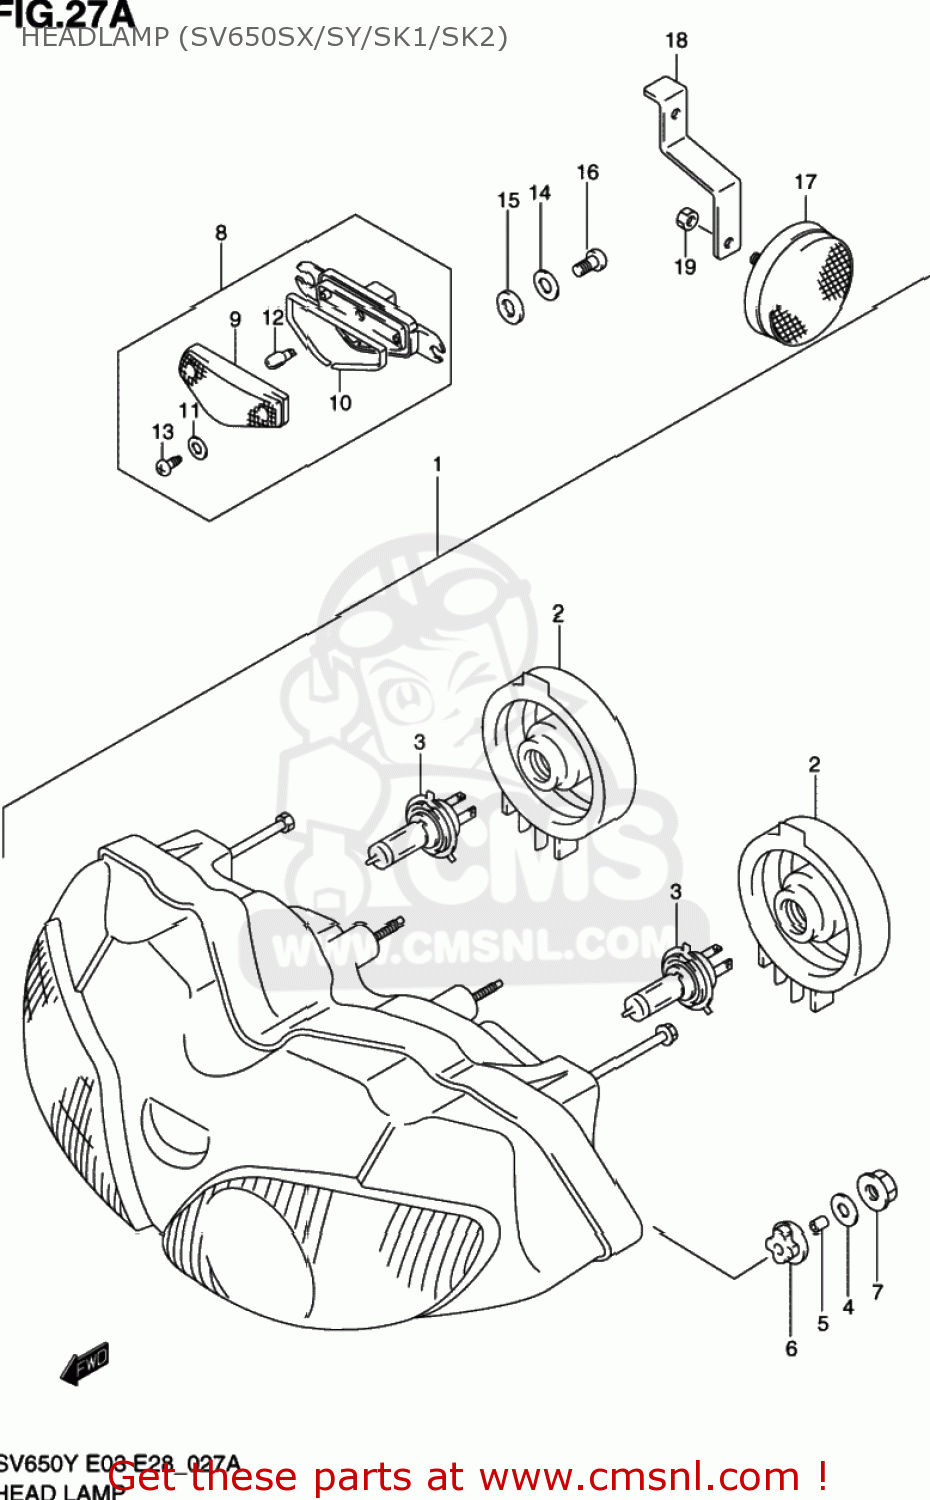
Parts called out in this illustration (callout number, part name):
1	HEADLAMP ASSY
2	COVER,SOCKET
3	BULB 12V 45/45W BF130-0
4	WASHER(6.5X20X1.6)
5	SPACER(6.5X9X12.5)
6	CUSHION
7	NUT
8	LAMP ASSY,FR POSITION
9	LENS
10	GASKET (NAS)
11	WASHER
12	BULB(12V5W)
13	SCREW
14	WASHER(5.5X18X1)
15	CUSHION
16	SCREW
17	REFLECTOR,REFLEX FR
18	BRACKET,FR SIDE RR
19	NUT
